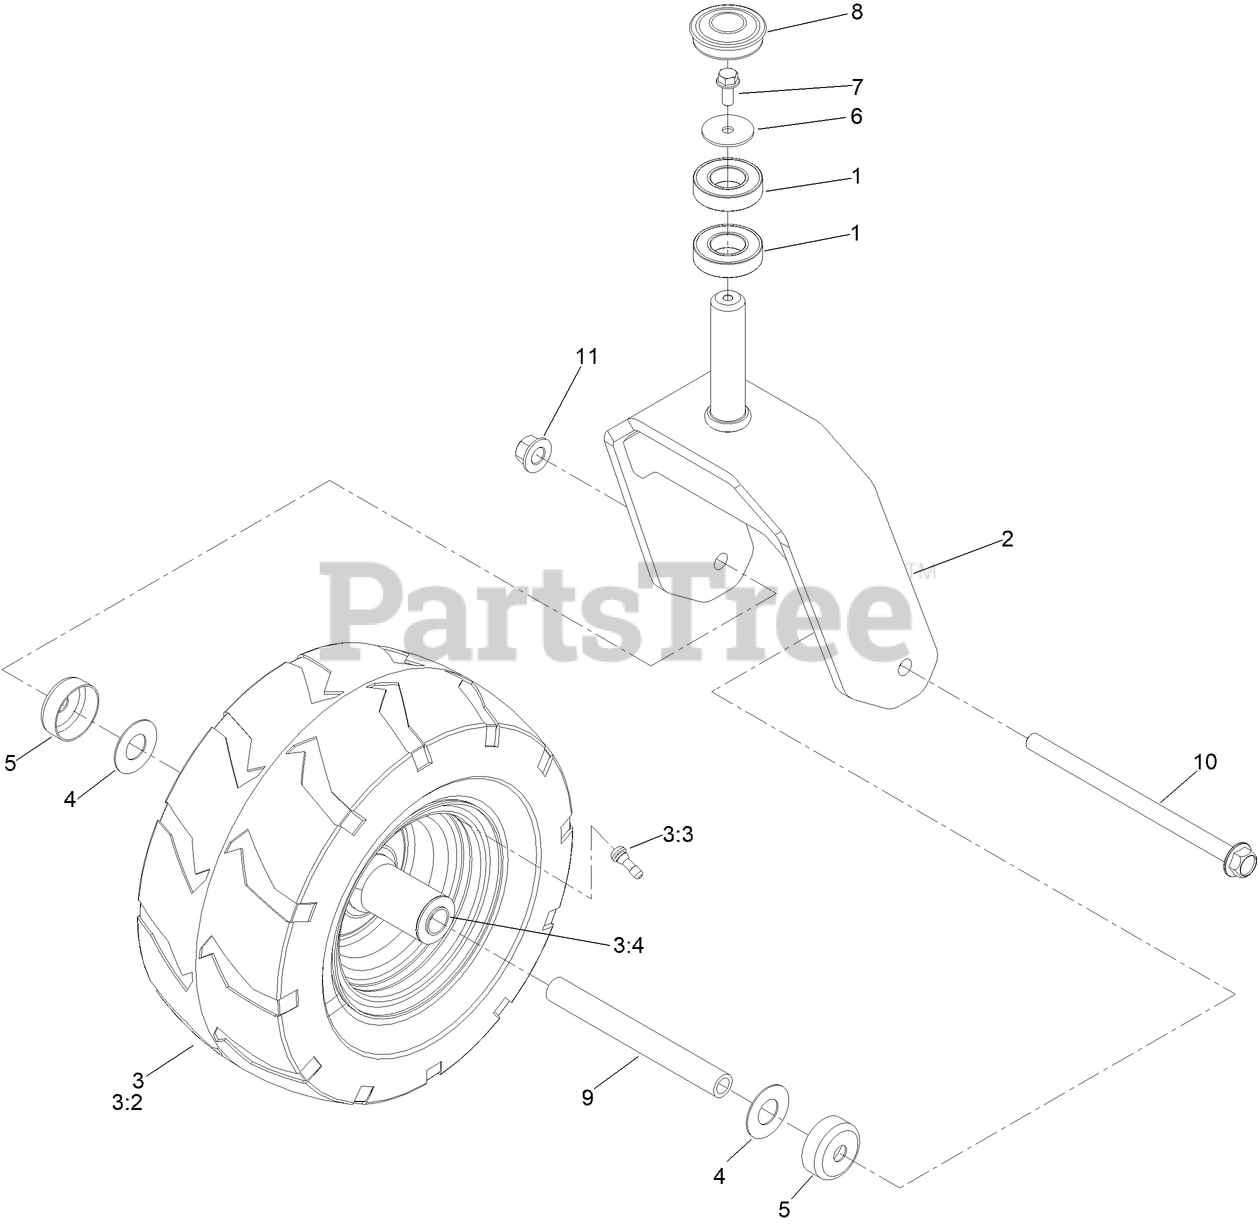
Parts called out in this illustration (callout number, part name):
1	BEARING-BALL
2	CASTOR FORK [RED]
3	TIRE AND WHEEL ASM
3:2	TIRE 13X6.5-6, TREADED
3:4	BEARING
4	WASHER
5	GUARD-SEAL
6	WASHER-FLAT
7	SCREW-HHF
8	CAP,GREASE
9	SPANNER-WHEEL
10	SCREW-HHF
11	NUT-HF
